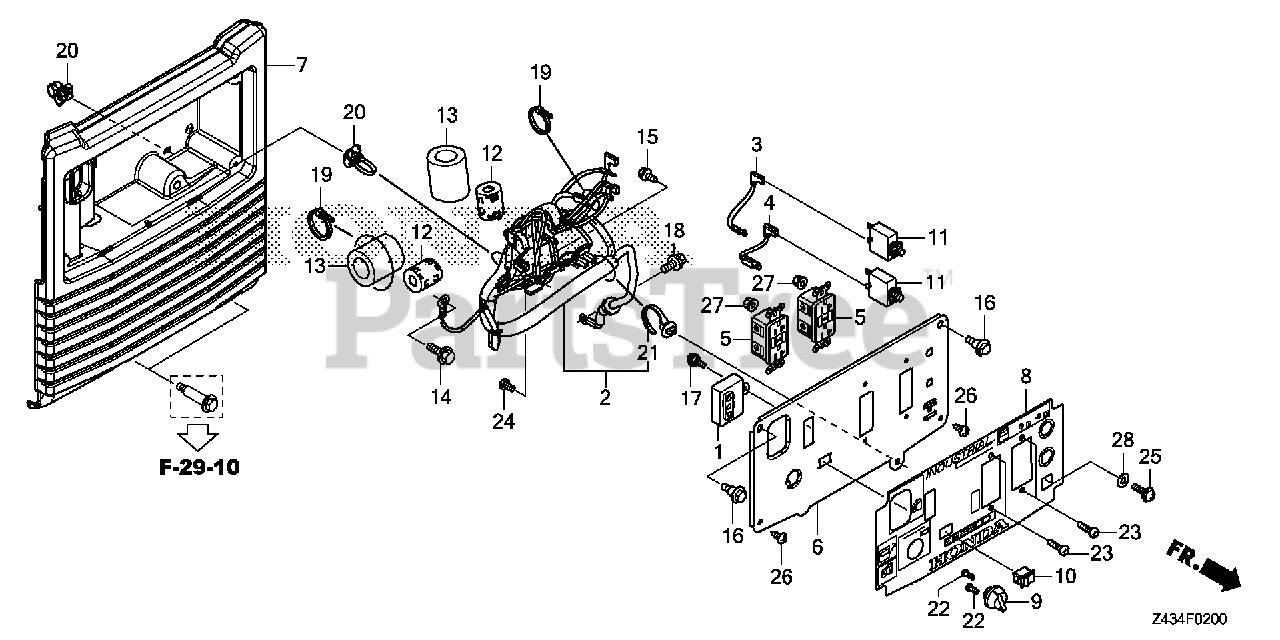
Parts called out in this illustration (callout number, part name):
1	IGNITION UNIT
2	WIRE HARNESS ASSY., CONTROL
3	WIRE, TERMINAL (200MM)
4	WIRE, TERMINAL (150MM)
5	RECEPTACLE (20A/125V) (GFCI)
6	PANEL, CONTROL
7	CASE, CONTROL PANEL *R280* (POWER RED)
8	MARK, CONTROL PANEL
9	SWITCH ASSY., ENGINE STOP
10	SWITCH, AUTO THROTTLE
11	PROTECTOR, CIRCUIT (20A) (WHITE)
12	FILTER, SUB NOISE (AC)
13	SUPPORTER, FILTER
14	BOLT, FLANGE (6X14)
15	SCREW, TAPPING (5X12)
16	BOLT, CONTROL PANEL
17	SCREW, PAN (5X13)
18	BOLT, GROUND (6X12) (SN)
19	TIE, CABLE
20	CLIP, WIRE HARNESS
21	CLIP, HARNESS BAND (145MM) (BLACK)
22	SCREW, PAN (3X8)
23	SCREW, PAN (4X10)
24	SCREW, PAN (5X8)
25	SCREW, PAN (5X16)
26	SCREW, TAPPING (5X12)
27	NUT, FLANGE (4MM)
28	WASHER, PLAIN (5MM)
